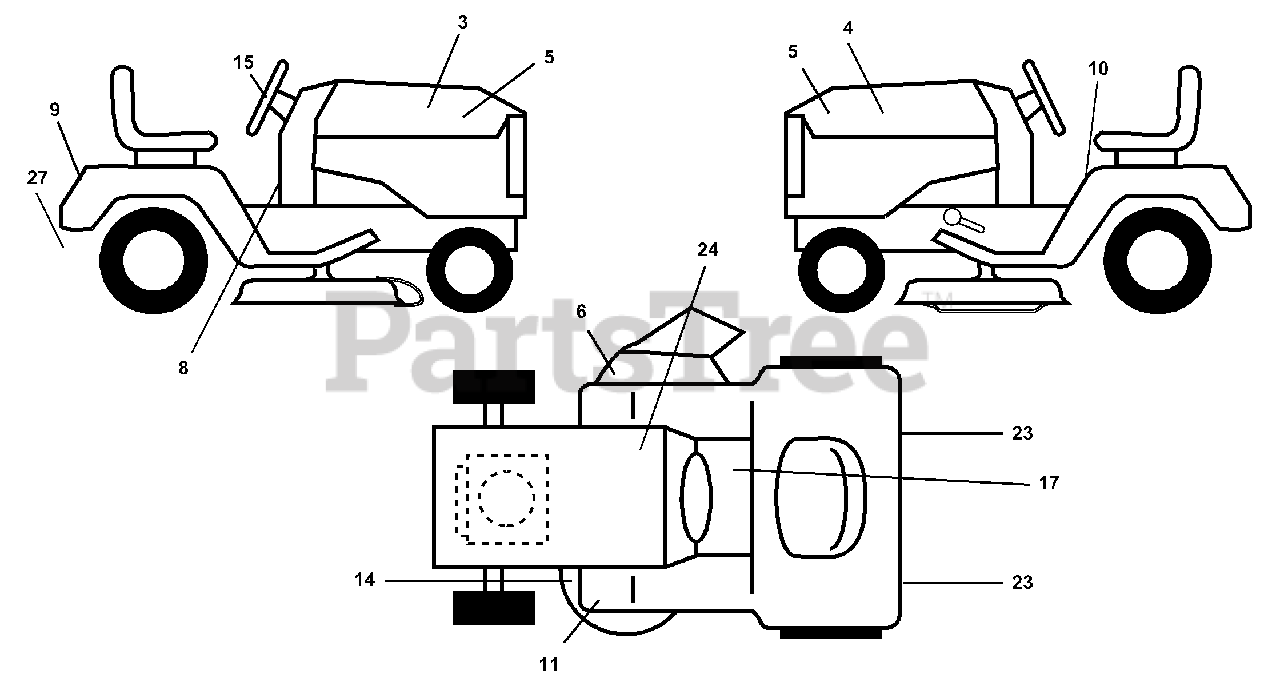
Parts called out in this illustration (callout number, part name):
3	Decal, Hood, RH
4	Decal, Hood, LH
5	Decal, Side Panel
6	Decal, Warning
8	Decal, Dash
9	Decal, Fender
10	Decal, Danger
11	Decal, Foot Rest
14	Decal, V-Belt Schematic
15	Decal, Ins. Strg Whl
17	Decal, Saddle Brake Parking
23	Reflector, Taillight
24	Decal, Btry Dngr/Psn
27	Decal, Drawbar
